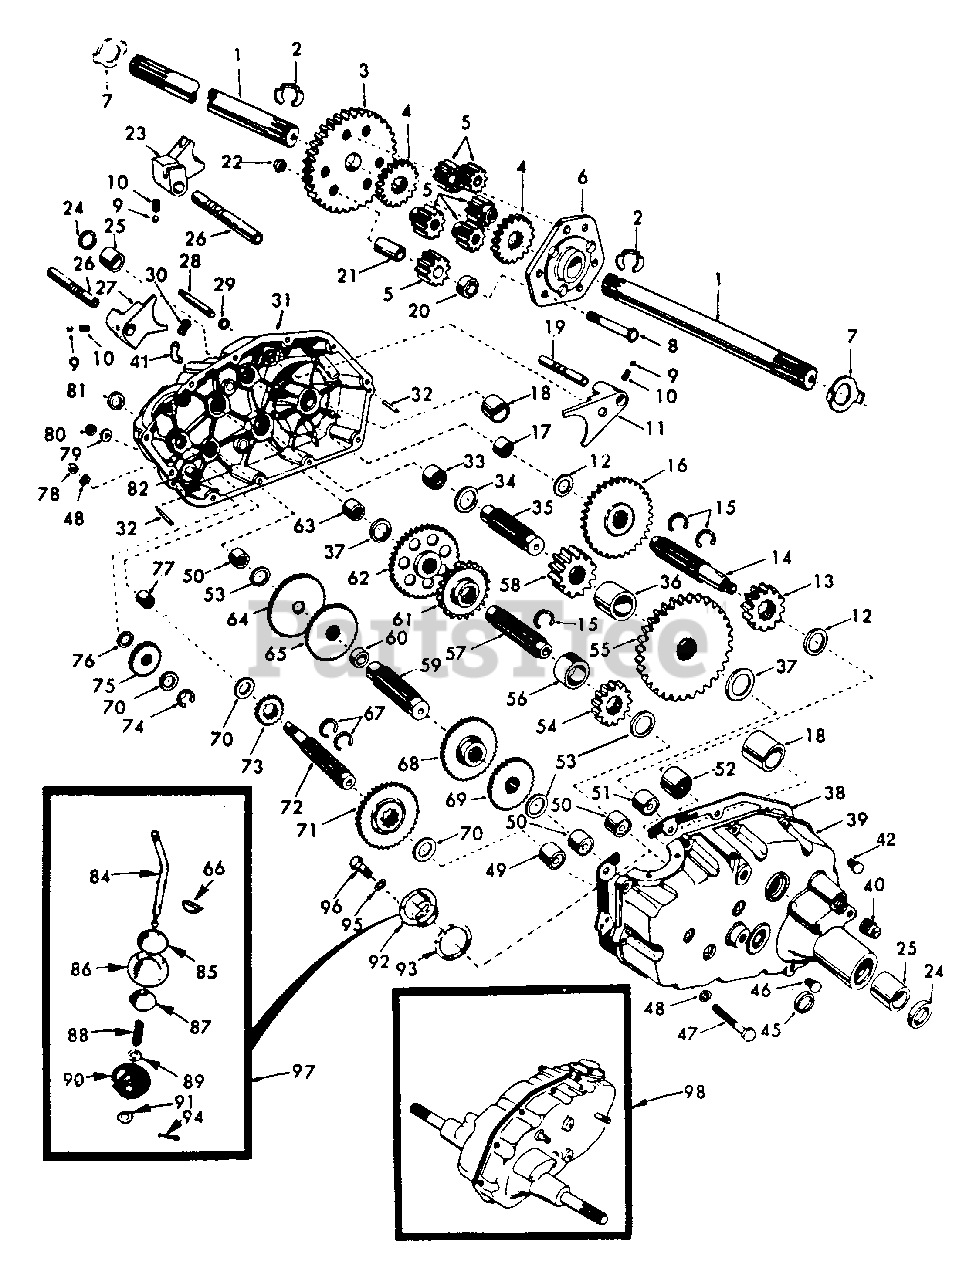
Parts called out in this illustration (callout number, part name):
1	Axle Shaft
2	Retaining, Ring
3	Final Drive Gear
4	Differential Gear
5	Differential Gear
6	Differential Carrier
7	Axle Thrust Washer
8	Hex, Bolt 3/8-24 x 3-1/4 (1" Thread Length)
9	Steel Ball
10	Spring Shift Fort Detent
11	Shift Fork, High-Low Range
12	Thrust Bearing Race
13	4th Reduction Pinion
14	3rd Reductin Gear Shaft
15	Snap Ring-Crescent Type
16	High-Low Range Gears
17	Needle Bearing
18	Sintered Iron Bearing
19	Shift Fork Shaft, High-Low Range
20	Differential Pinion Spacer
21	Differential Pinion Bushing
22	Gripco Centerlock Nut 3/8-24
23	Shift Fork, L.H.
24	Oil Seal
25	Sintered Iron Bearing
26	Shift Fork Shaft
27	Shift Fork, R.H.
28	Shift Shaft, High-Low Range
30	Pressure Relief Valve
31	Gearcase, Reverse Idler Shaft and Bearings, R.H.
33	Needle Bearing
34	Thrust Bearing Race
35	4th Reduction Gear Shaft
36	4th Reduction Gear Spacer
37	Thrust Bearing Race
38	Gearcase Gasket
39	Gearcase and Bearings, L.H.
40	Pipe Plug 1/2-14 N.P.T.
41	Elbow, Street 90
42	Bolt, Hex 5/16-18 UNC x 1-5/8
46	Pipe Plug 1/4-18 N.P.T.
47	Hex Bolt 5/16-18 x 1-1/2 Grade 5
48	Lockwasher 5/16 Extra Heavy
49	Needle Bearing
50	Needle Bearing
51	Needle Bearing
52	Needle Bearing
53	Thrust Bearing Race
54	3rd Reduction Pinion-Low
55	4th Reduction Gear
56	3rd Reduction Pinion Spacer
57	2nd Reduction Gear Shaft
58	Final Drive Pinion
59	1st Reduction Gear Shaft
60	1st Reduction Shaft Spacer
61	3rd Reduction Pinion High
62	2nd Reduction Gear
63	Needle Bearing
64	Low Speed Gear and 2nd Reduction Pinion Cluster
65	Reverse Gear
66	Key-Hi-Pro 1/8 x 17/32
67	Snap Ring Crescent Type
68	Intermediate Speed Gear
69	High Speed Gear
70	Thrust Bearing Race
71	Intermediate and High Speed Cluster Pinions
72	Input Shaft
73	Low Speed Pinion
75	Reverse Idler Gear
76	Reverse Idler Thrust Washer
77	Needle Bearing
78	Hex, Nut 5/16-18
79	Sealing Washer
80	Hex, Jam Nut 7/16-20
81	Oil Seal
82	Reverse Idler Shaft
84	Gear Shift Lever Bent
85	Gear Shift Cap
86	Gear Shift Ball Cover and Pin
87	Shift Lever Guide Ball Keyed
89	Washer 15/32 x 15/16 x 16 Ga.
90	Shift Mechanism Seal
91	Washer 9/16 x 15/16 x 12 Ga.
92	Gear Shift Gate and Reinforcement
93	Shift Ball Cover Gasket
94	Cotter Pin 1/8 x 3/4
95	Lockwasher 5/16
96	Hex, Bolt 5/16 x 18 UNC x 7/8
97	Gear Shift Lever Assembly
98	Transaxle Assembly Less Brake Drum Shift Lever
